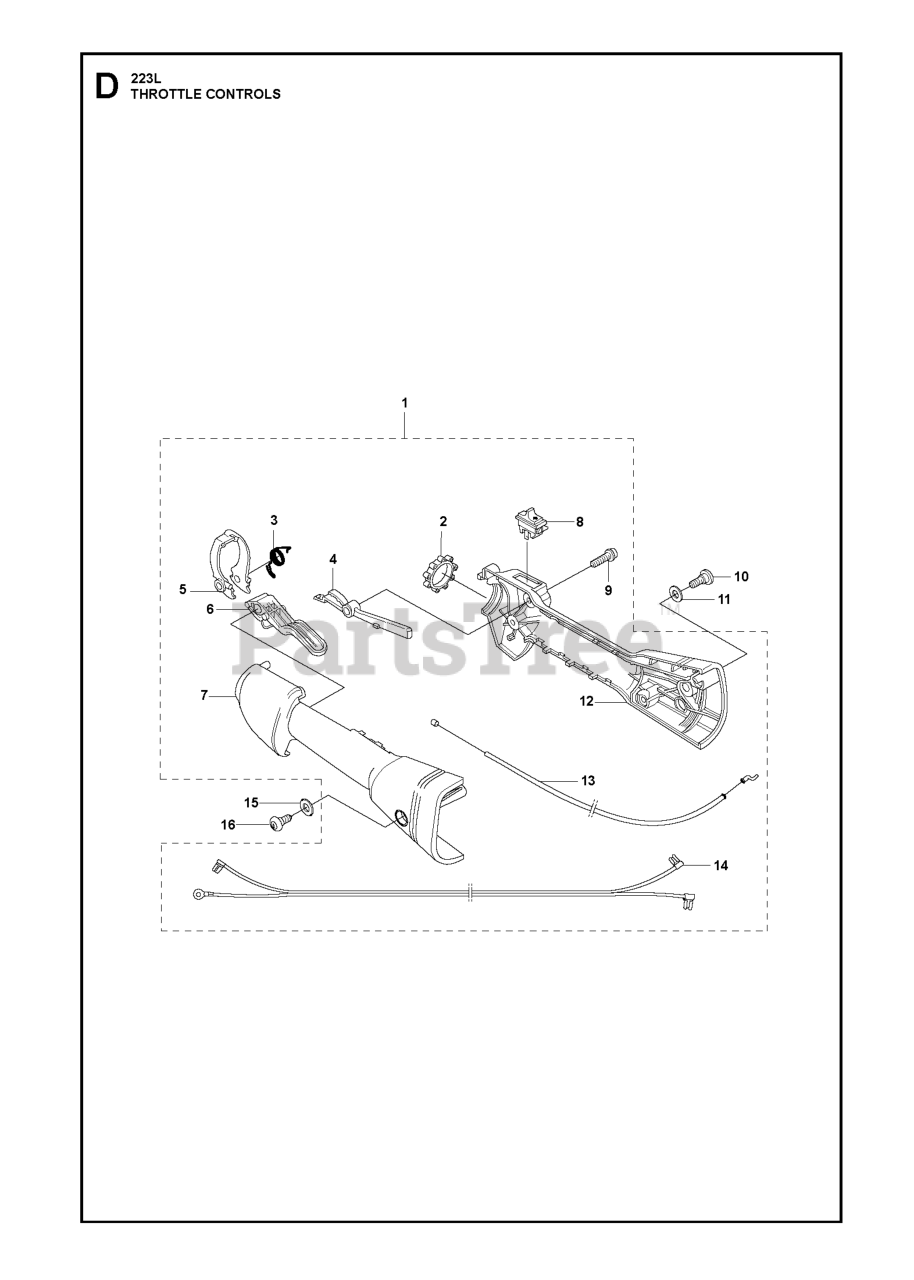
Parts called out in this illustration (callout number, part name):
1	THROTTLE TRIGGER CPL
2	VIBRATION DAMPER
4	THROTTLE LOCK
6	THROTTLE TRIGGER
7	HANDLE HALF HSG LH
8	STOP BUTTON
10	SCREW SPACER
11	O-RING 8X1.6
12	HSG THROTTLE RH
13	THROTTLE CABLE
14	SHORT-CIRCUIT CABLE
15	O-RING 8X1.6
16	SCREW SPACER
